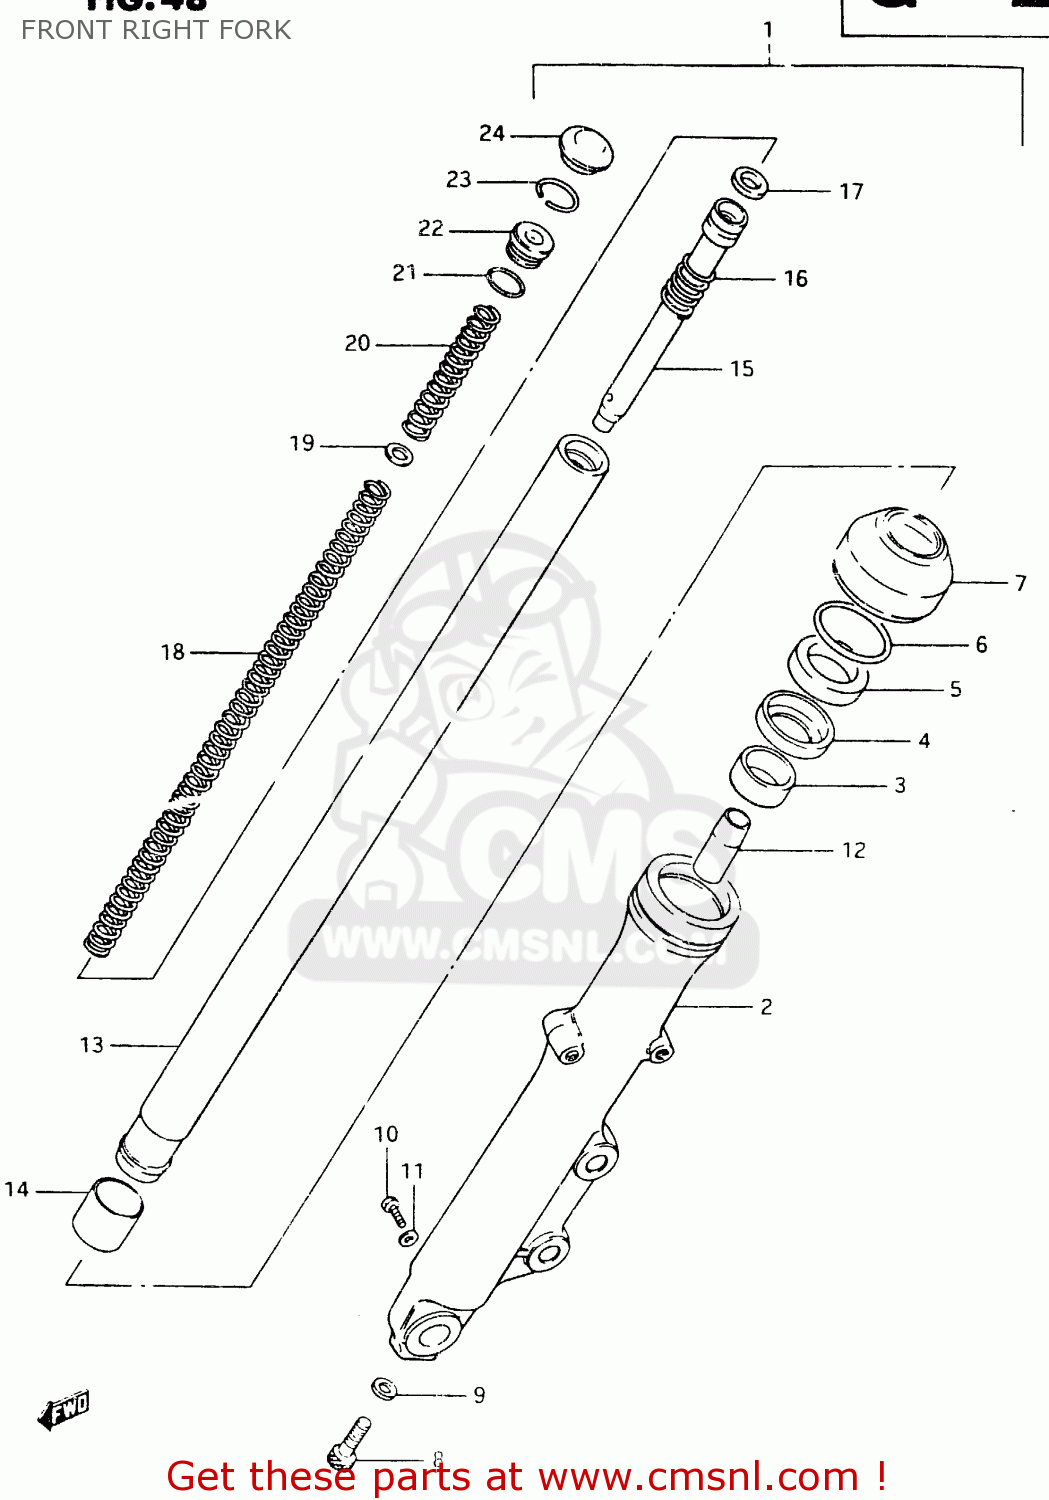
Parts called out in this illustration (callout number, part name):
1	DAMPER ASSY, RH
2	OUTER TUBE RH
3	BUSH,GUIDE
4	SPACER,OIL SEAL
5	OIL SEAL,FRONT FORK
6	CIRCLIP,FORK OIL SEAL
7	DUST SEAL
8	BOLT(8X27)
9	GASKET (NAS)
10	BOLT
11	GASKET,DRAIN,PLUG (NAS)
12	PIECE,OIL LOCK
13	INNER TUBE
14	BUSH
15	CYLINDER
16	SPRING,REBOUND
17	RING,PISTON
18	SPRING (B)
19	SEAT,SPRING
20	SPRING A
21	O RING
22	SEAT,SPRING
23	RING,STOPPER
24	CAP
